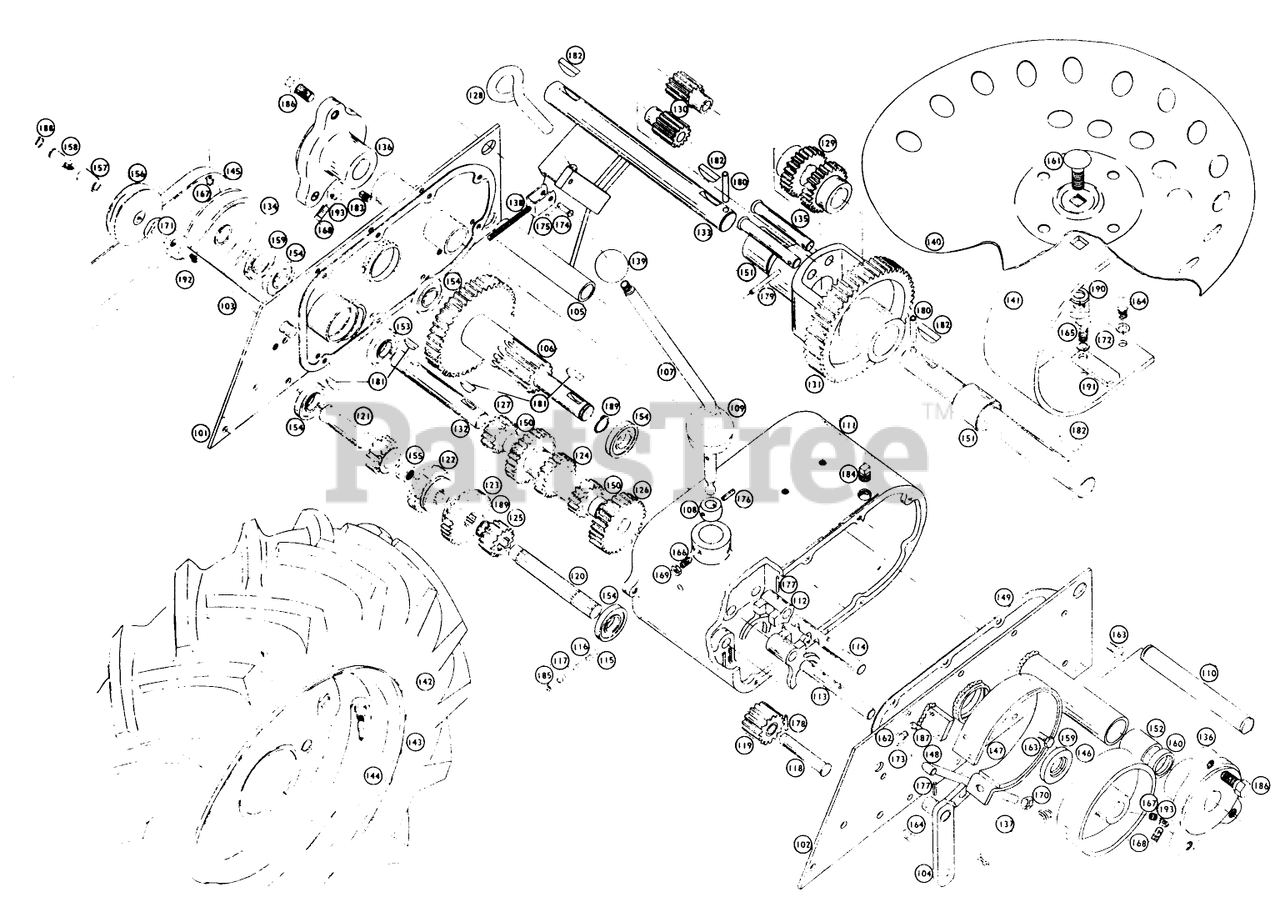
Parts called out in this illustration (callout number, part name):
101	Right Trans. Cover
102	Left Trans. Cover
103	Idler Arm
105	Hitch
109	COVER-DUST
110	Hitch Pin
111	Trans. Hsg
112	FORK-SHIFT
115	BALL-DETENT
119	Rev. Idler Gear
120	Spline Shaft
125	GEAR
126	GEAR-CLUSTER SHAFT
132	Cluster Shaft
134	PULLEY
141	Seat Spring
142	T T Assembly
144	Rim
146	Brake Drum
148	Brake Rod
150	BUSHING-BRONZE
155	BEARING-NEEDLE
157	Bronze Bearing
158	Stud-Idler Pin
161	Carriage Bolt
162	Hex Head Cap
163	Hex Head Cap
164	Hex Head Cap
165	Hex Head Cap
166	SETSCREW
167	Snap Ring
168	Set Screw Sq. Head
170	Hex Nut
172	Lockwasher
173	Cotter Key
175	Cotter Pin
176	Roll Pin
177	Roll Pin
179	RoIl Pin
180	31500 1967 OPC
182	Woodruff Key #15
183	Pipe Plug
185	CUP-PLUG
187	Lockwasher, 1/4
188	Snap Ring
190	Lockwasher
191	Lug-Cable
193	31300 '65-67&UP 20
